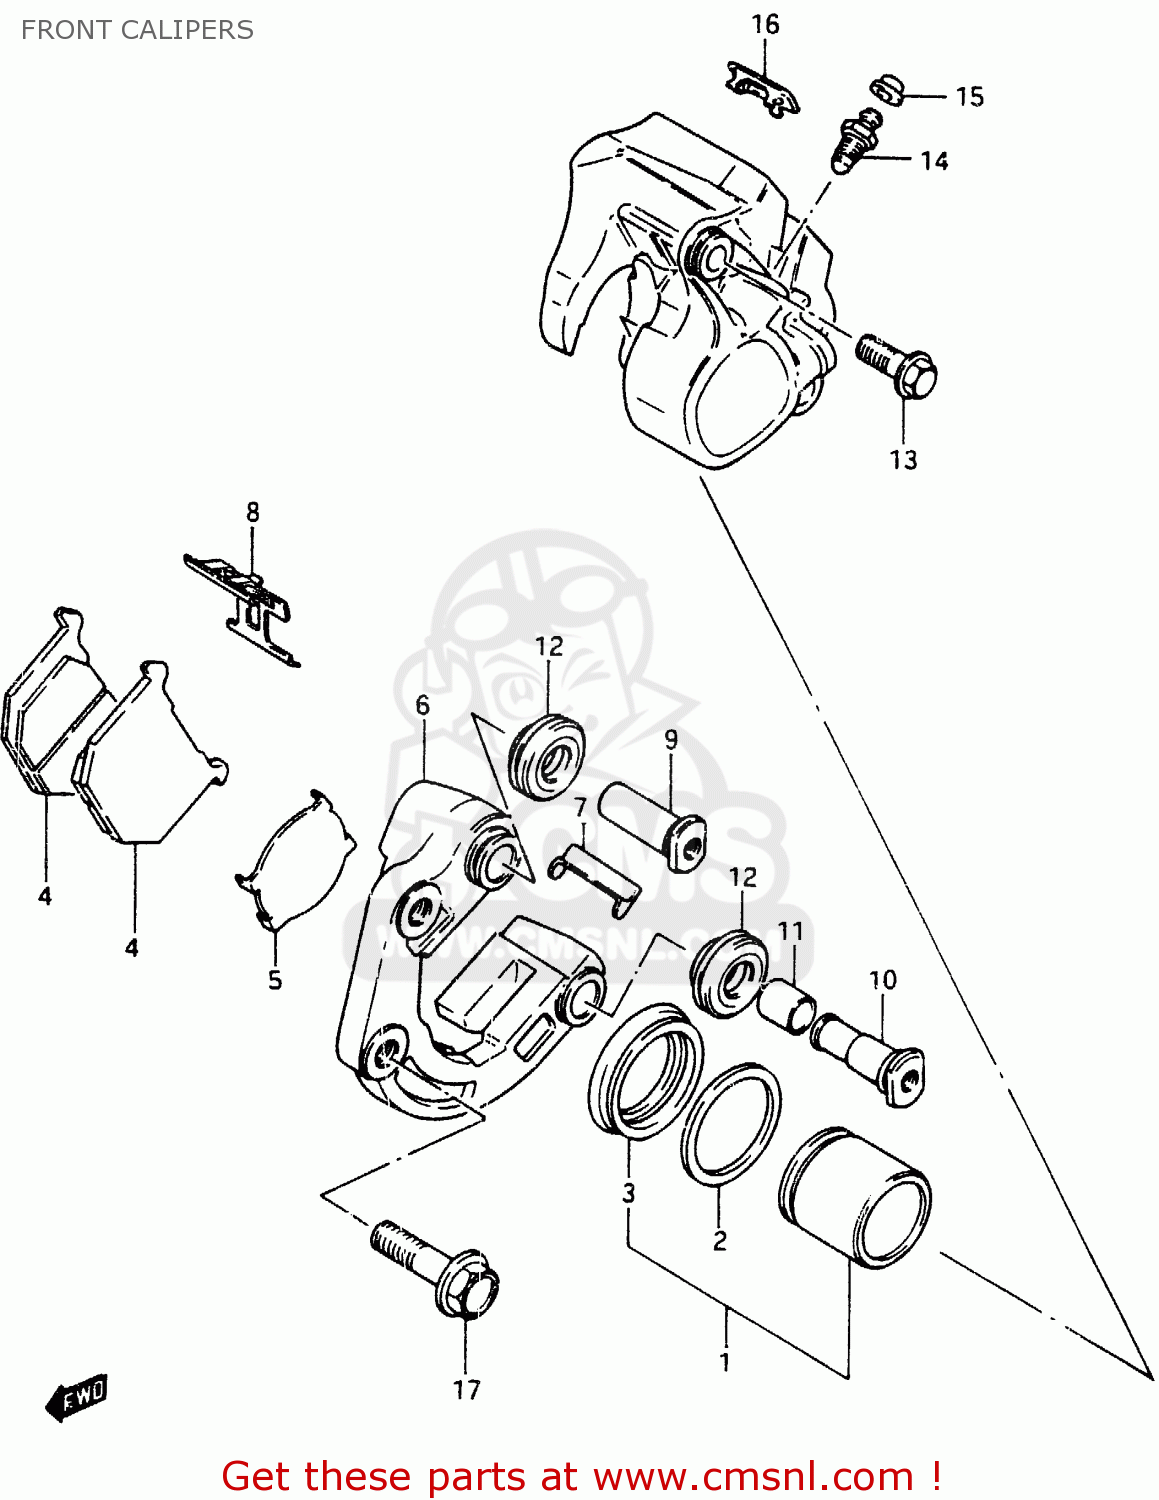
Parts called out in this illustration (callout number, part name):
1	PISTON SET
2	SEAL,PISTON
3	BOOT,PISTON
4	PAD
5	SHIM,PAD
6	CARRIER,CALIPER,LEFT
7	GUIDE,PAD
8	SPRING,PAD
9	AXLE NO.1
10	AXLE NO.2
11	BUSH,AXLE
12	BOOT,AXLE
13	BOLT
14	BLEEDER
15	CAP,BREATHER
16	COVER
17	BOLT 10X40
